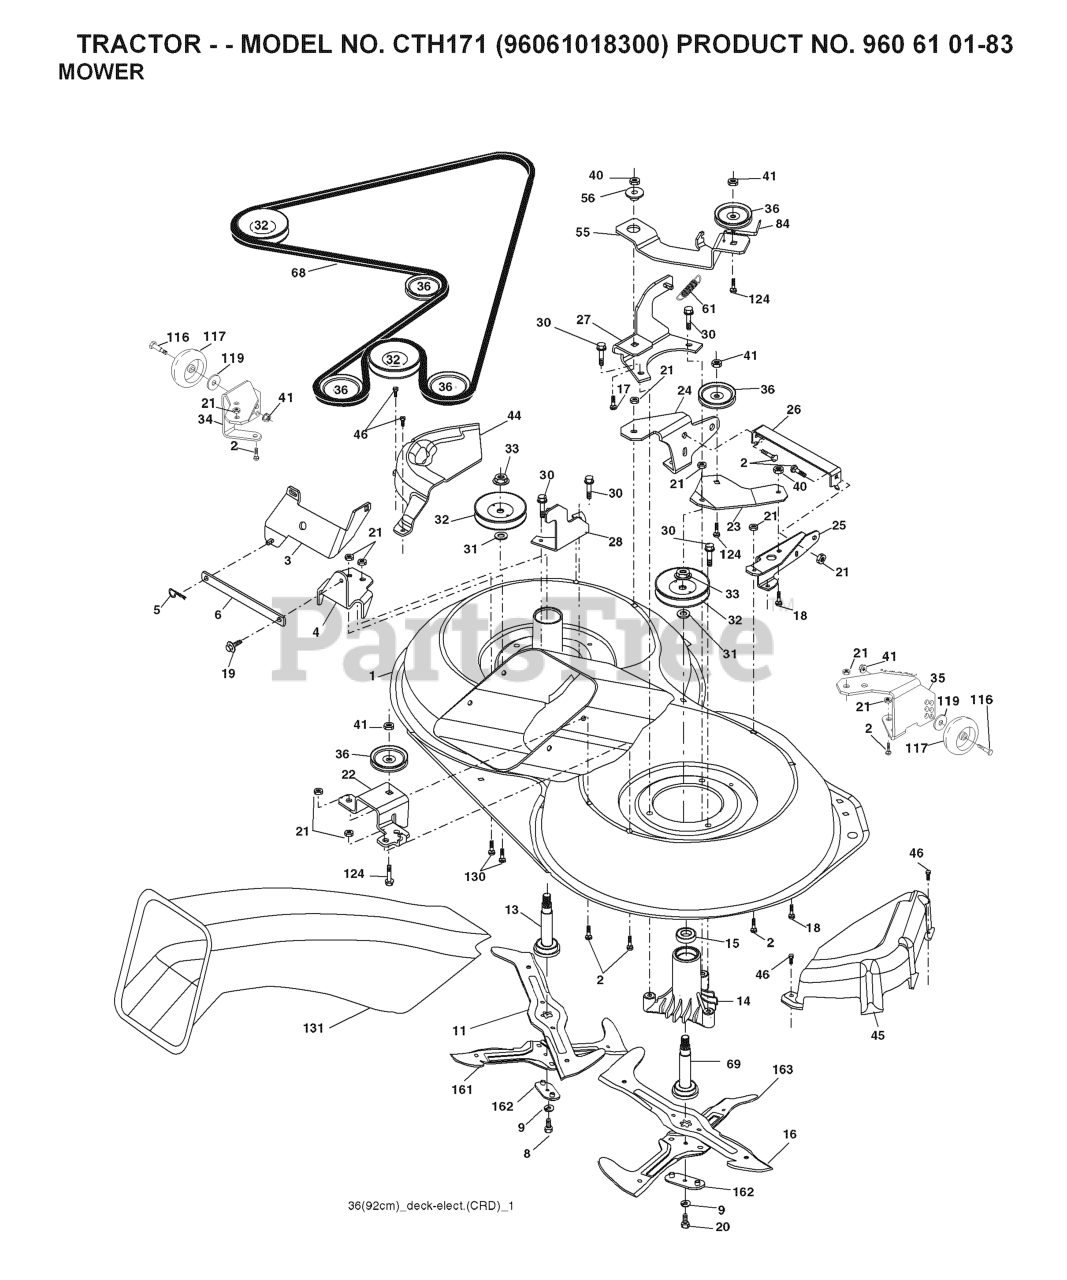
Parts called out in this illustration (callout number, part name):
2	RP BOLT 5/16-18 X3/4 ZN/YEL GR
5	RETAINER-SPRNG RB
6	BAR.SWAY.92.CRD
8	BOLT.3/8-24X1.25 GR8
9	LOCKWASHER
13	SHAFT ASM VENT
14	HOUSING.MANDREL.VENTED (MACHD)
17	BOLT.3/8-14X1.25
18	BOLT
19	BOLT SHD 5/16-18
20	BOLT.3/8-24X1.25GR8. LHTHRD
21	LOCKNUT
26	SUPPORT
30	SCREW, WASHER HEAD
31	WASHER.SPACER.MANDREL
33	NUT.FLANGE.LOCK.TOP
36	PULLEY.IDLER.4.25
41	NUT LOCK FLG 3/8-16 UNC
45	COVER.MANDREL.RH.CRD
46	SCREW.1/4-20X5/8
55	ARM.IDLER.92 CRD.2006
56	SPACER.RETAINER.MOWER
61	SPRING
68	BELT.DRIVE.92CM.CRD.2006
69	SHAFT.ASM.W/LWR.BRG.RH.THREAD
84	KEEPER, BELT IDLER
116	BOLT.SHOULDER.3/8-16X3-5/8.
117	RP WHEEL. GUAGE RALLY
118	LOCKNUT
119	WASHER
124	BOLT.3/8-16X1.50
130	BOLT.CARR.SQNK.5/16-18UNC.X3/4
131	CHUTE BAGGER
